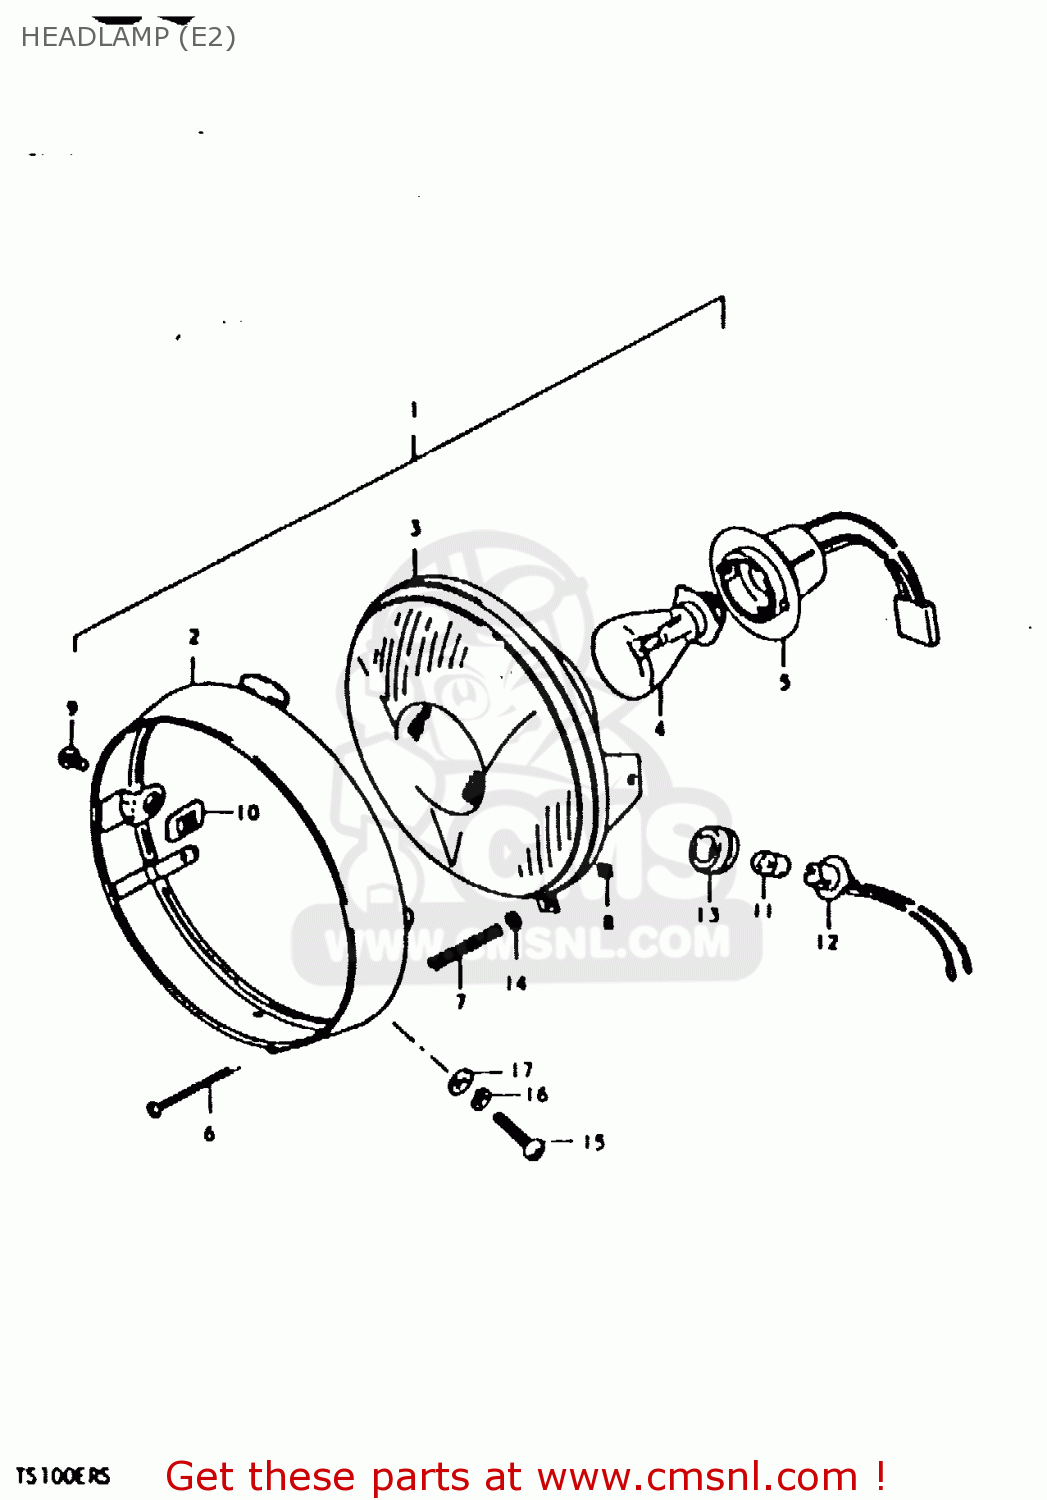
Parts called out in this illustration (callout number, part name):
1	HEADLAMP ASSY
2	RIM
3	UNIT
4	BULB(6V25/25W,STANLEY,A7007)
5	SOCKET
6	SCREW,HEADLAMP ADJUST
7	SPRING
8	NUT,HEADLAMP ADJUSTER
9	SCREW
10	NUT
11	BULB(6V/3W)
12	SOCKET
13	SEAL,PARKING BULB
14	WASHER
15	SCREW
16	LOCK WASHER
17	WASHER
